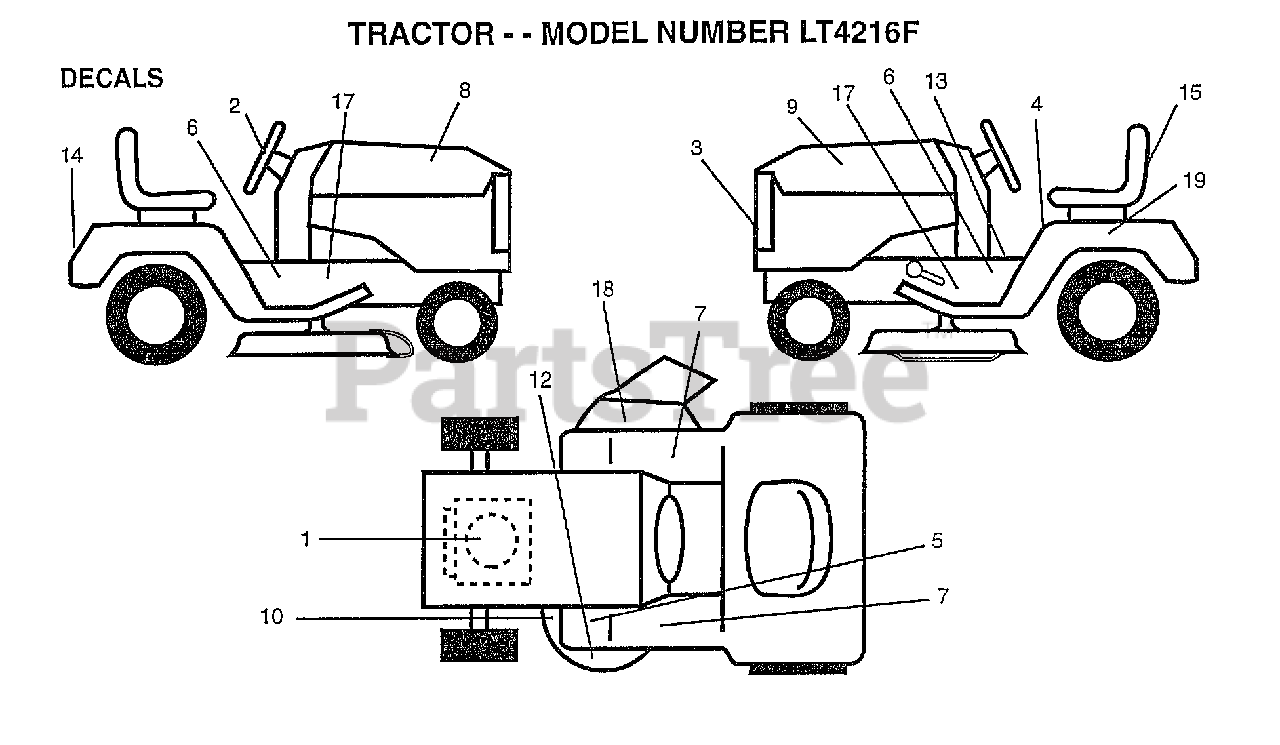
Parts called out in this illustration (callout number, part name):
1	DECAL, HP ENGINE
2	DECAL INST WHL
3	DECAL LOGO GRILLE
4	DECAL CAUT FEND
5	DECAL CLUT/BRAKE
6	DECAL CHASSIS KGR
7	FOOTREST PAD
8	DECAL HOOD RH
9	DECAL HOOD RH
10	DECAL
12	DECAL.DECK.KGRO.
13	DECAL.SADDLE.INST
14	DECAL.FEND.KGRO
17	DECAL.CHAS.KGRO
18	DECAL DANGER CT/F
19	DECAL.BTRY.DANGER
